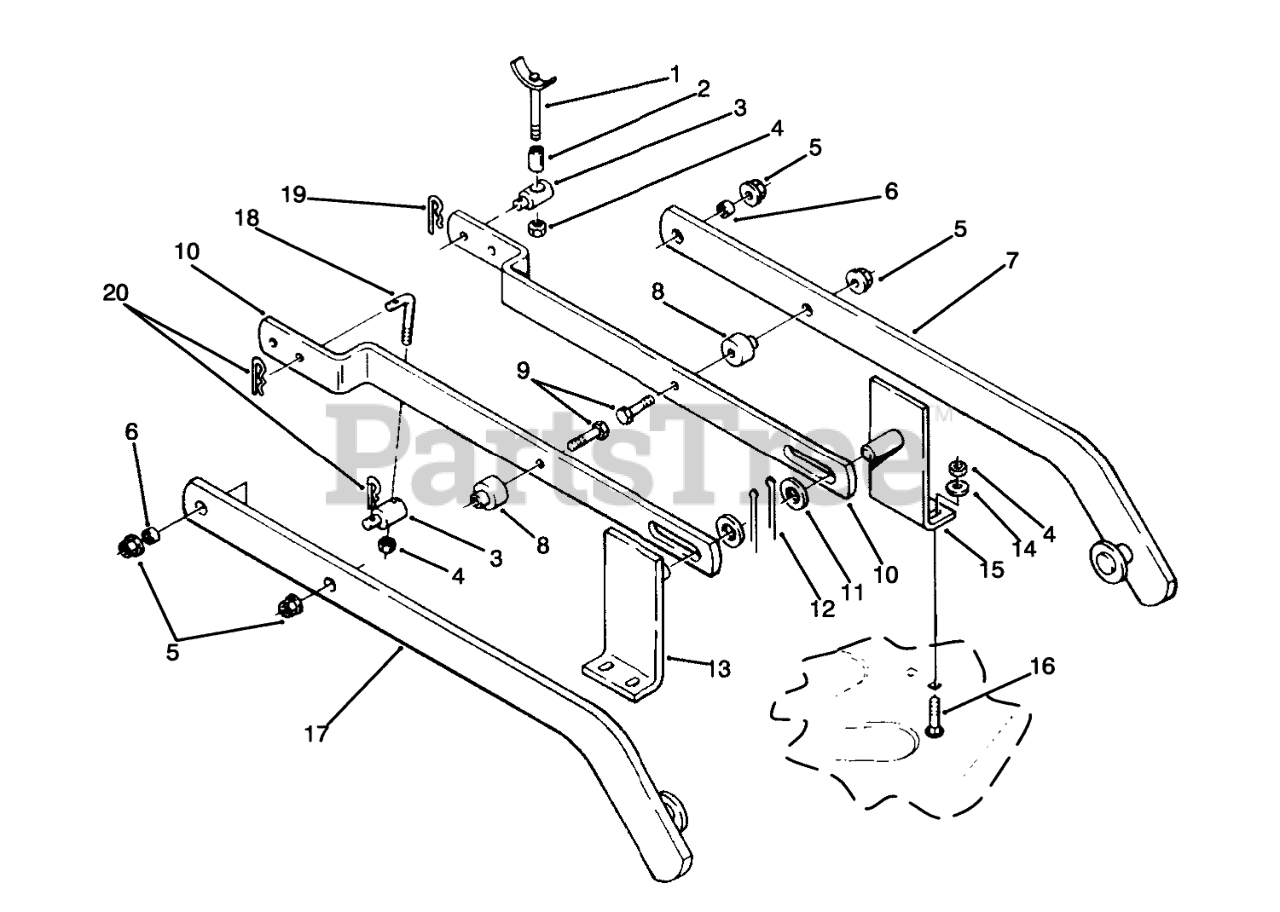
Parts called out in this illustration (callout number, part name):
1	WLDMT-HANGER ROD
2	SPACER .375 ID X 1.6
3	Trunion
4	NUT-LOCK, NI
5	LOCKNUT-FLANGE
6	SPACER
7	Draft Bar LH
8	SPACER
9	SCREW-HH
10	Bar-Leveler
11	WASHER-FLAT
12	PIN-COTTER
13	Bracket RH
14	WASHER-FLAT
15	Bracket
16	BOLT-CARR
17	Draft Bar RH
18	ROD-LIFT
19	Hairpin
20	PIN-COTTER
